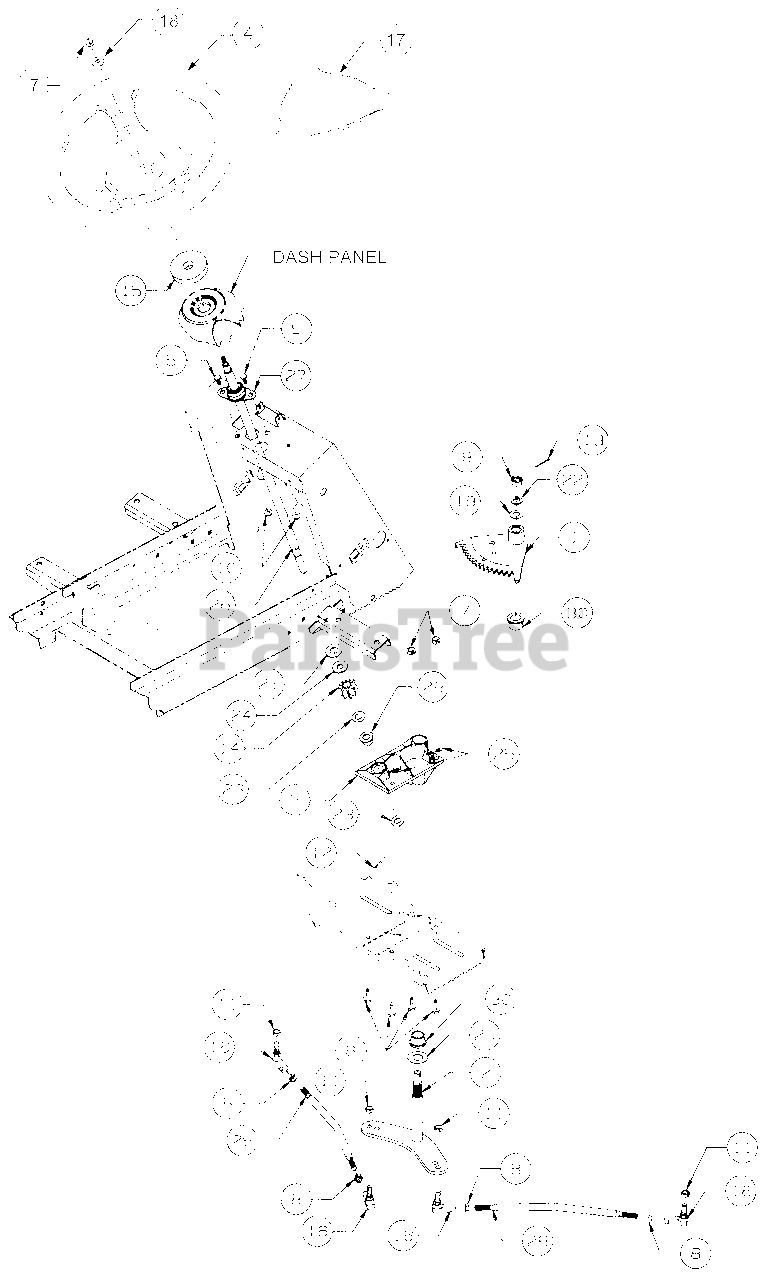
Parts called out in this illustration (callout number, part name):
1	Segment Assy, 18T Steering
2	Arm Assy, Lower Steering
3	Housing Assy,
4	Wheel, Steering, Soft Grip
5	Screw, Hex Cap, 1/4 - 20 x .62, GR5
6	Screw, Hex Wash. Hd. Tapp 5/16 - 18 x .75
7	Nut, Hex Center Lock, 5/16-18
8	Nut, Hex Jam, 3/8-24 GR2
9	Nut, Hex Slotted, 1/2-20 GR5
10	Nut, Hex Flange Lock, 1/4-20
11	Nut, Hex Lock, 3/8-24 GR5
12	Pin, Cotter, 1/8 Dia x 1
13	Pin, Cotter, 3/32 Dia x 1.25
14	Pinion, Steering
15	Gasket, Steering
16	Joint, Ball, 3/8-24
17	Insert, Steering Wheel Cover
18	Washer, Bell, .340 x .88 x .06 Thk
19	Washer, Flat, .510 x 1 x .06 Thk
20	Washer, Flat, .760 x 1.5 x .03 Thk
21	Washer, Flat, .56 x 1 x .04 Thk
22	Washer, Lock, 1/2
23	Washer, Flat, .531 x 1 x .027 Thk
24	Washer, Rubber Flat, .50 x 1.12 x .125 Thk
25	Fitting, Grease, 3/16 Drive Type
26	Shaft, Steering
27	Bearing, Flange
29	Bearing, Flange, .503 ID
30	Bearing, Bronze Flange, .75 ID
